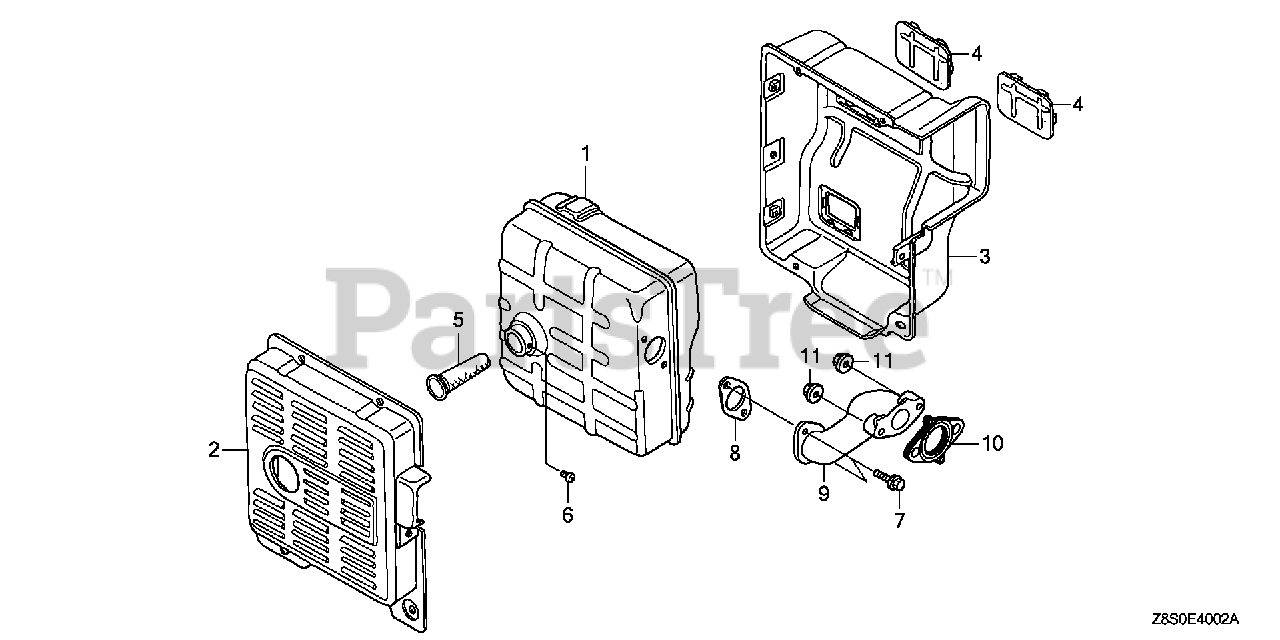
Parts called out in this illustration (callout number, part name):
1	MUFFLER (TSURUMI)
2	PROTECTOR, MUFFLER (OUTER)
3	PROTECTOR, MUFFLER (INNER)
4	SEAL, MUFFLER PROTECTOR
5	ARRESTER, SPARK
6	SCREW, TAPPING (4X8)
7	BOLT, FLANGE (8X20) Use up to Engine SN 1609606.
8	GASKET, EX. PIPE
10	GASKET, EX. PIPE
11	NUT, FLANGE (8MM)
